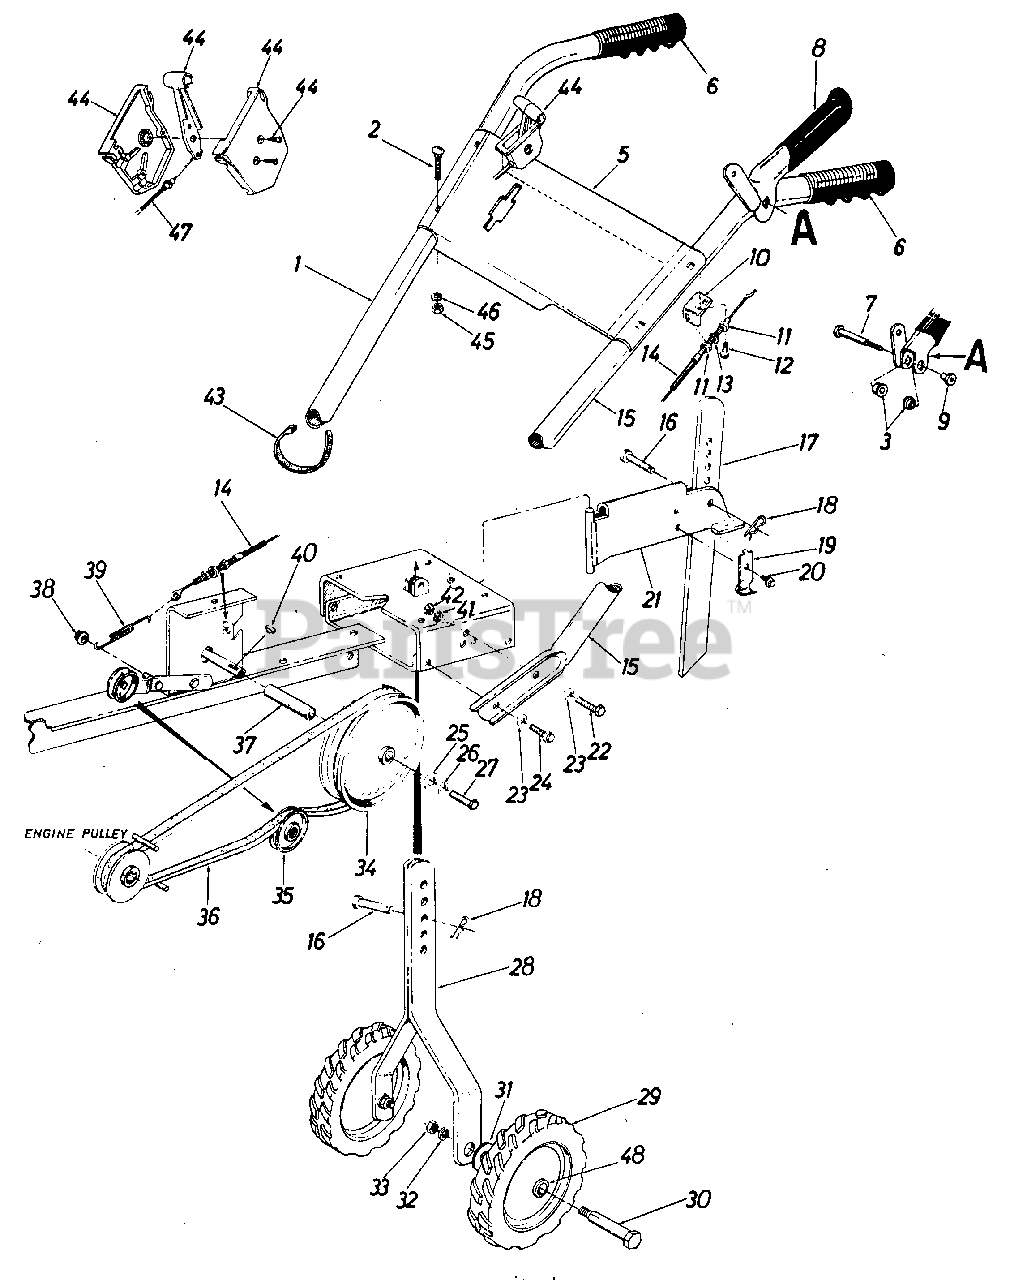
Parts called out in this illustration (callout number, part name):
1	Handle R.H.
2	Carriage Bolt 5/16-18 x 1.75" Lg.
3	Hex Flange Plastic Brg.
5	Handle Panel
6	Grip
7	Shld. Bolt .38" Dia.
8	Clutch Grip Ass'y.
9	Shld. Nut 1/4-20 Thd.
10	Cable Support Brk't.
11	Hex Jam Nut 5/16-24 Thd.
12	Hex Wash. Hd. Self-Tap Scr. 1/4-20 x .50" Lg.
13	L-Wash. 5/16" I.D.
14	Clutch Control Cable
15	H and I e L.H.
16	Clevis Pin
17	Depth Bar
18	Hairpin Cotter
19	Depth Bar Spring
20	Hex Wash. Hd. Self-Tap Scr. 1/4-20 x .50" Lg.
21	Tailpiece Ass'y.
22	Hex Scr. 3/8-16 x 1.00" Lg.
23	Belleville Wash. 3/8" I.D.
24	Hex Wash. Hd. Self-Tap Scr. 3/8-24 x 7/8" Lg.
25	Fl-Wash. .25" I.D. x .930" O.D. x .120" Thk.
26	L-Wash. 1/4" I.D.
27	Hex Scr. 1/4-28 x .75" Lg.
28	Wheel Bracket Ass'y.
29	Wheel Ass'y. 10 x 1.75
30	Shld. Bolt
31	Belleville Washer 1/2" I.D.
32	L-Wash. 1/2" Scr.
33	Hex Nut 1/2-20 Thd.
34	Pulley 6.00" O.D.
35	Idler Pulley
36	V-Belt 1/2" Pitch x 39"
37	Spacer
38	Cap Speed Nut
39	Extension Spring
40	Hi-Pro Key
41	L-Wash. 3/8 Scr.
42	Hex L-Nut 3/8-16 Thd.
43	Cable Ties
44	Throttle Control Box
45	Hex Nut 5/16-18 Thd.
46	L-Wash. 5/16" Scr.
47	Throttle Control Wire 35"
48	Bearing
